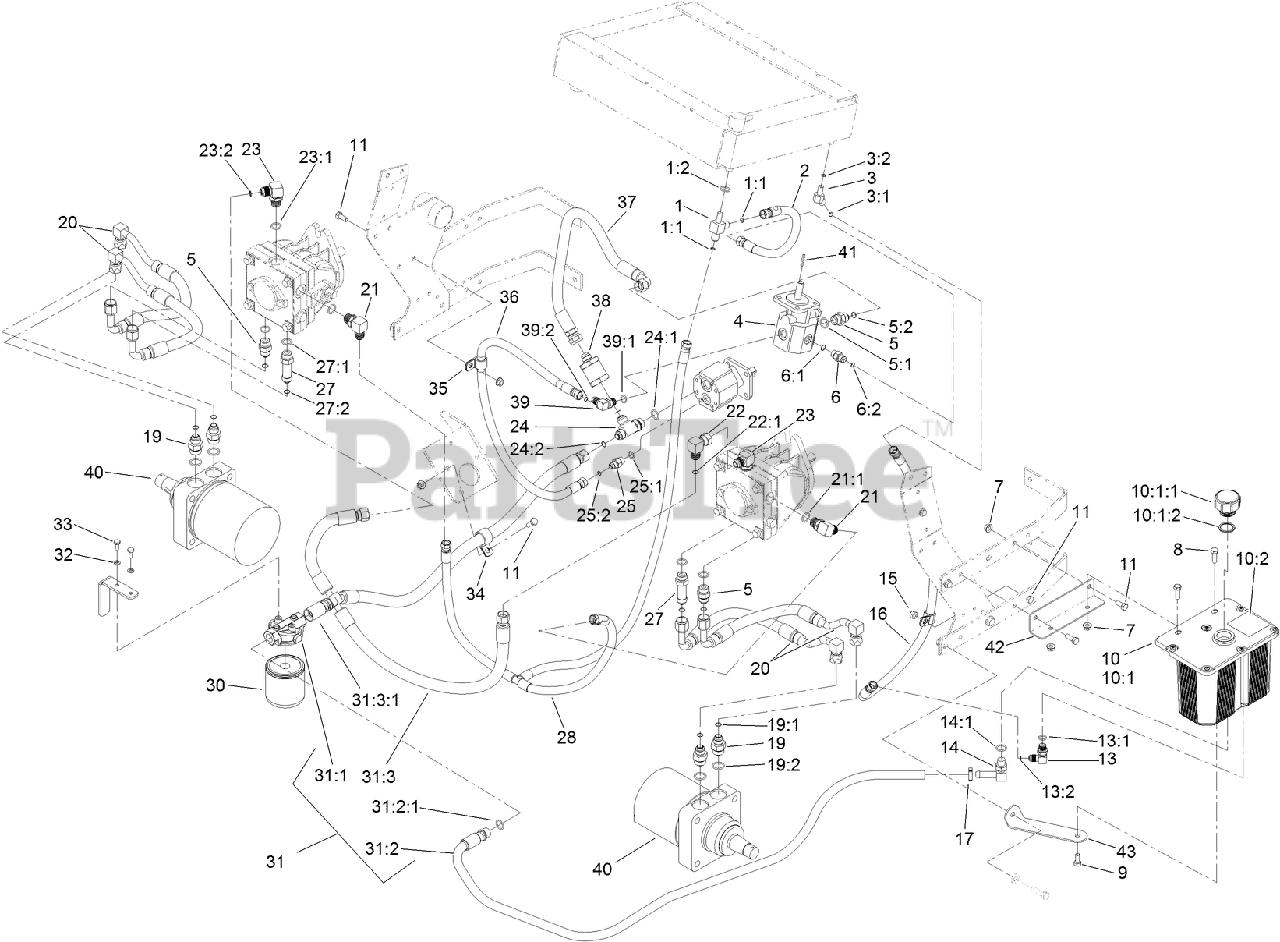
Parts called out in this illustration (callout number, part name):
1	FITTING-HYD, STRAIGHT TEE
1:1	O-RING
1:2	O-RING
2	FAN CASE DRAIN HOSE ASM
3	FITTING-HYD, 45 ELBOW
3:1	O-RING
3:2	O-RING
4	MOTOR-FAN, COOLING
5	FITTING-STRAIGHT
5:1	O-RING
5:2	O-Ring
6	FITTING-STRAIGHT
6:1	O-RING
6:2	O-RING
7	NUT-HF
8	SCREW-HH
9	SCREW-HH
10	HYDRAULIC TANK ASM
10:1	TANK-HYDRAULIC
10:1:1	CAP-RESERVOIR, HYD
10:1:2	GASKET-CAP
10:2	DECAL-TANK, HYD
11	SCREW-HH
13	FITTING-90 DEG
13:1	O-Ring
13:2	O-RING
14	FITTING-ELBOW, 90 DEG
14:1	O-RING
15	NUT-LOCK, NI
16	TANK RETURN HOSE ASM
17	CLAMP-HOSE
19	Fitting-Straight
19:1	O-RING
19:2	O-Ring
20	HYD HOSE ASM
21	FITTING-ELBOW, 90 DEG
21:1	O-RING
22	FITTING-90 DEG
22:1	O-Ring
23	FITTING-90 DEG
23:1	O-RING
23:2	O-Ring
24	FITTING-TEE
24:1	O-RING
24:2	O-Ring
25	FITTING-STRAIGHT
25:1	O-Ring
25:2	O-RING
27	ADAPTER-HYD, STRAIGHT
27:1	O-RING
27:2	O-Ring
28	CASE DRAIN HOSE ASM
30	FILTER-OIL, HYDRAULIC
31	CHARGE HOSE ASM
31:1	HEAD-FILTER
31:2	FILTER INLET HOSE ASM
31:2:1	O-RING
31:3	PUMP INLET HOSE ASM
31:3:1	O-RING
32	WASHER-LOCK
33	SCREW-HH
34	CLIP-LOOM
35	CLIP-LOOM
36	AUXILLARY PUMP HOSE ASM
37	HOSE-PRESSURE, HIGH
38	FILTER-IN LINE, 50 MICRON
39	FITTING-90 DEG
39:1	O-Ring
39:2	O-RING
40	MOTOR-WHEEL, HYD
41	KEY-SQUARE
42	BRACKET-TANK MOUNT, UPPER
43	BRACKET-TANK MOUNT, LOWER
